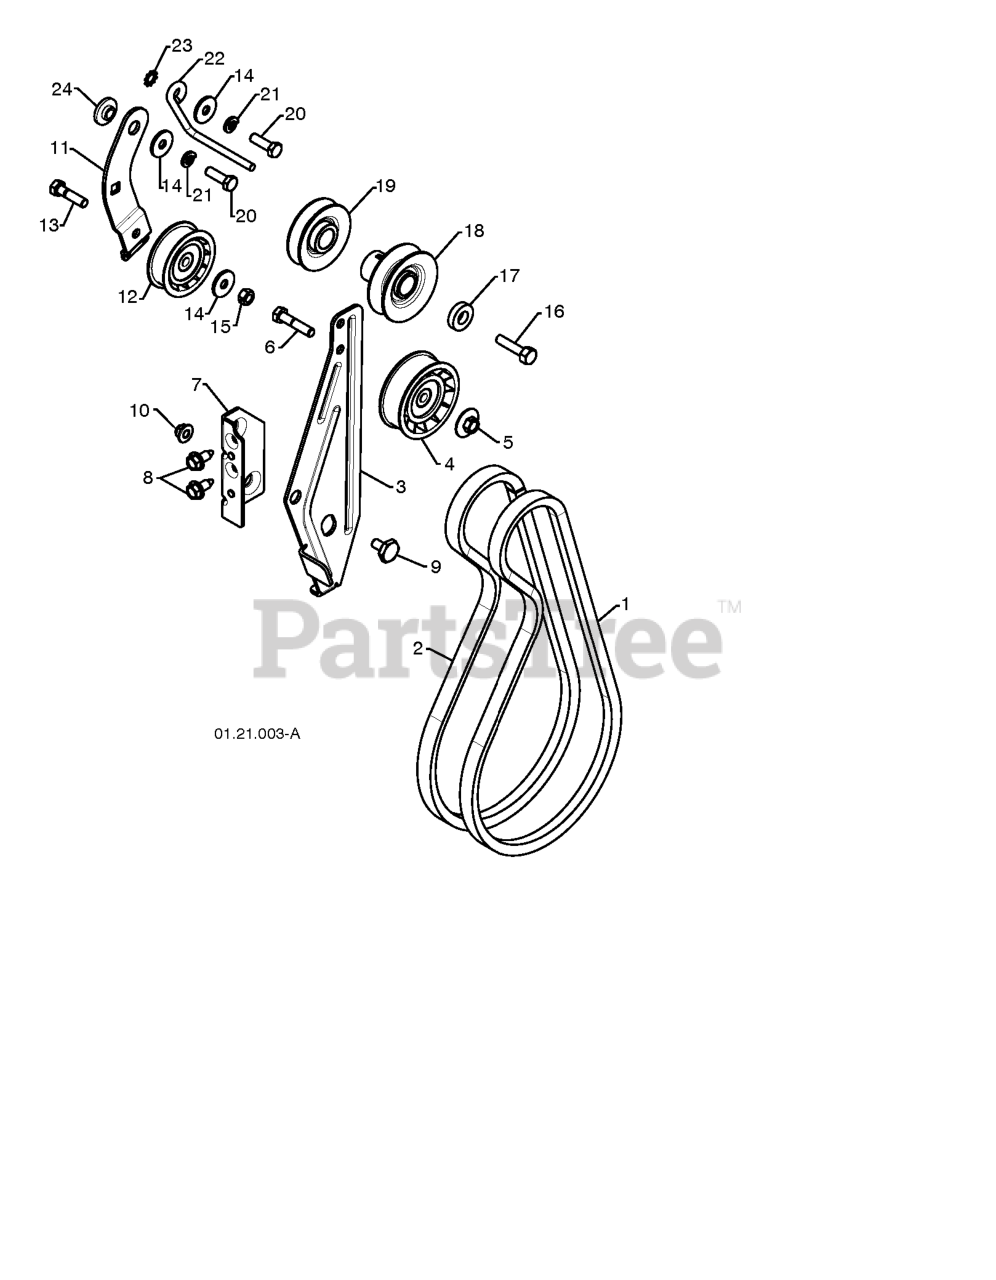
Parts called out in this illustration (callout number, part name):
1	BELT.V.IMPELLER
2	V-BELT TRACTION 34.25
3	ARM.IDLER.BRAKE.
4	PULLEY.W/SPACER.2.75
5	NUT.FLANGE.HEX.5/16X18.BLACK
6	HEX BOLT
7	RP BRACKET.IDLER.PIVOT
8	BOLT.HEX.HD.WASHER.5/16-18X.75
9	BOLT.SHOULDER.1/2X12
10	NUTNYLOK.FLRANGE.5/16-18
11	ARM, IDLER
12	PULLEY.W/SPACER.2.25
13	BOLT.5/16-18X1-1/4 FULL.THREAD
14	STEEL WASHER
15	NUT.CENTERLOCK.5/16-
16	SCREW, HEX HD 3/8-24 X 1-3/8
17	WASHER, FLAT 3/8
18	PULLEY.IMPELER.
19	PULLEY.ENG.TRACTION
21	WASHER.LOCK.HVY.HLCL.SPR.5/16
22	BELT.GUIDE.RH
23	WASHER EXT TOOTH LOCK 5/16
24	RP BUSHING, IDLER PIVOT
